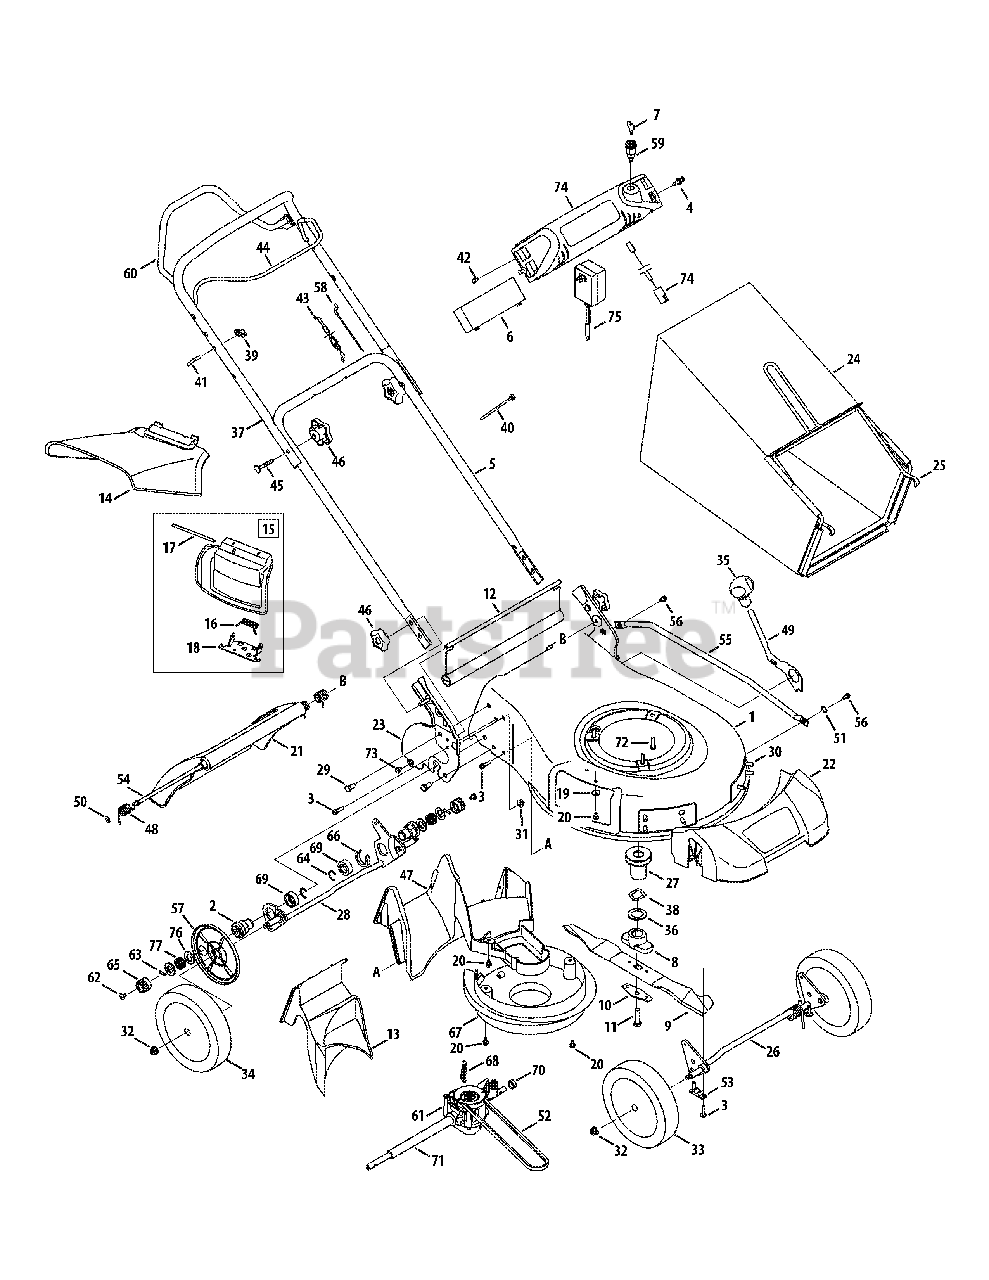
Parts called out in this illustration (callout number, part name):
2	Transmission Support Bearing
3	Screw, 1/4-15 x 1.000
5	Lower Handle
6	Battery
8	Blade Adapter
9	Mulching Blade
10	Blade Bell Support
11	Screw, 3/8-24 x 1.50
12	Trailing Shield
13	Rear Mulch Plug
14	Side Discharge Chute
15	Mulch Plug (Incl. 16-18)
16	Torsion Spring
17	Hinge Pin
18	Chute Deflector Adapter
19	Belleville Washer
22	Front Cover
23	Handle Bracket - RH
23	Handle Bracket - LH
25	Grass Bag Frame
26	Front Bracket Assembly
27	Pulley Assembly, Drive
28	Self Propelled Bracket Assembly
29	Hhcs, 5/16-18 x .625
30	Screw, 5/16-14 x .750
31	Nut, Flange Lock, 5/16-18
32	Nut, Flange Lock, 3/8-16
33	Front Wheel
34	Rear Wheel
35	Height Adjuster Knob
36	Washer, Flat, 1.031 x .620 x .095
37	Upper Handle
38	Washer, Wave, 1.5 x 1.0 x .029
39	Handle Knob
40	Cable Tie
41	Rope Guide
42	Screw, #10-16 x .750
43	Control Cable
44	Blade Control
45	Bolt Carriage, 5/16-18 x 2.0
46	Star Knob
47	Rear Baffle
48	Door Torsion Spring - RH
48	Door Torsion Spring - LH
49	Spring Lever
51	Washer, Wave, .385 ID x .598 OD
53	Bushing, Lock, .505 Dia. X .62
54	Rear Door Pivot Rod
55	Cross Bracket
56	Scr., Shldr., 1/4-20 x .50
57	Wheel Dust Cover
58	Drive Cable
59	Key Switch
60	Drive Control
61	Transmission
62	Screw, 1/4-20 x .390
63	Dowel Pin
64	Retainer Ring
65	Spur Gear - RH
65	Spur Gear - LH
66	Spacer, Clip
67	Engine Baffle
68	Extension Spring, .429OD x 2.515
69	Bearing Support Spacer
70	Sleeve Spacer, .550ID x .340 Lg.
71	Sleeve Spacer, .550ID x 7.97 Lg.
72	Screw, 3/8-16 x 1.00
73	Screw, #10-16 x .500
74	Electric Start Harness Assembly
75	Battery Charger
75	Battery Charger (w/LED Light)
76	Washer, Flat, .508 x 1.00 x .020
77	Spring, WaveS
